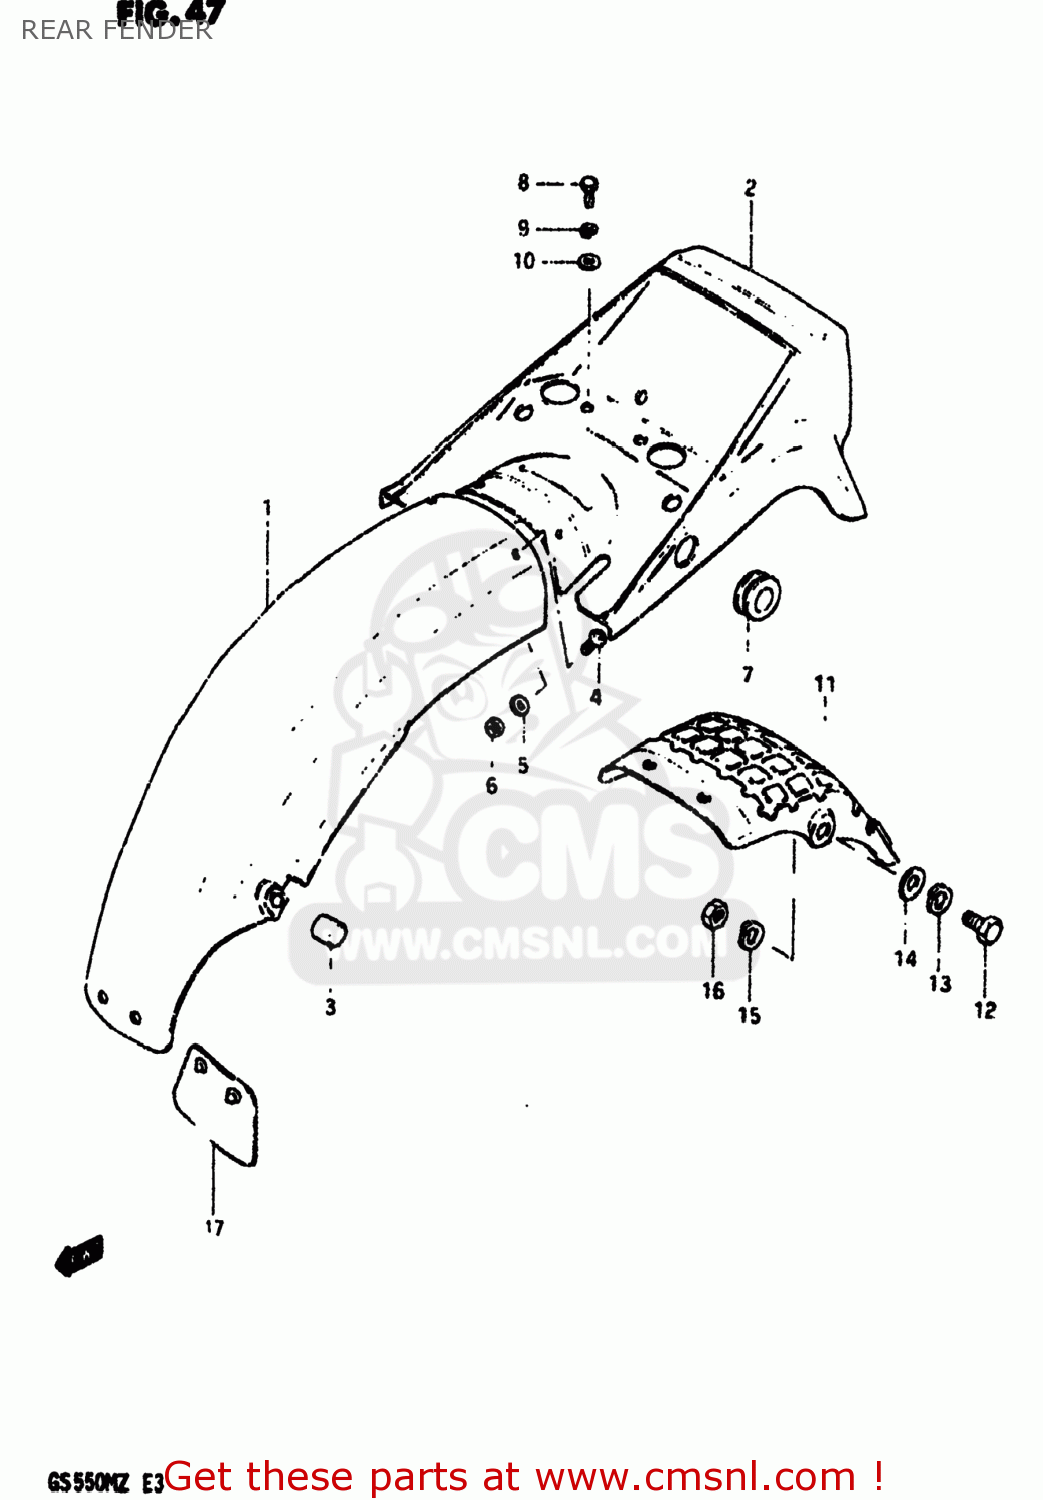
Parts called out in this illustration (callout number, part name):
1	FENDER,REAR
2	FENDER,REAR
3	CUSHION
4	SCREW
5	WASHER (5.5X16X1.2)
6	NUT
7	GROMMET,SEAT LOCK HOLE
8	BOLT
9	LOCK WASHER
10	WASHER
11	REINFORCEMENT,REAR FENDER
12	BOLT
13	LOCK WASHER
14	WASHER
15	LOCK WASHER
16	NUT
17	GUIDE,RR FENDER MUD
